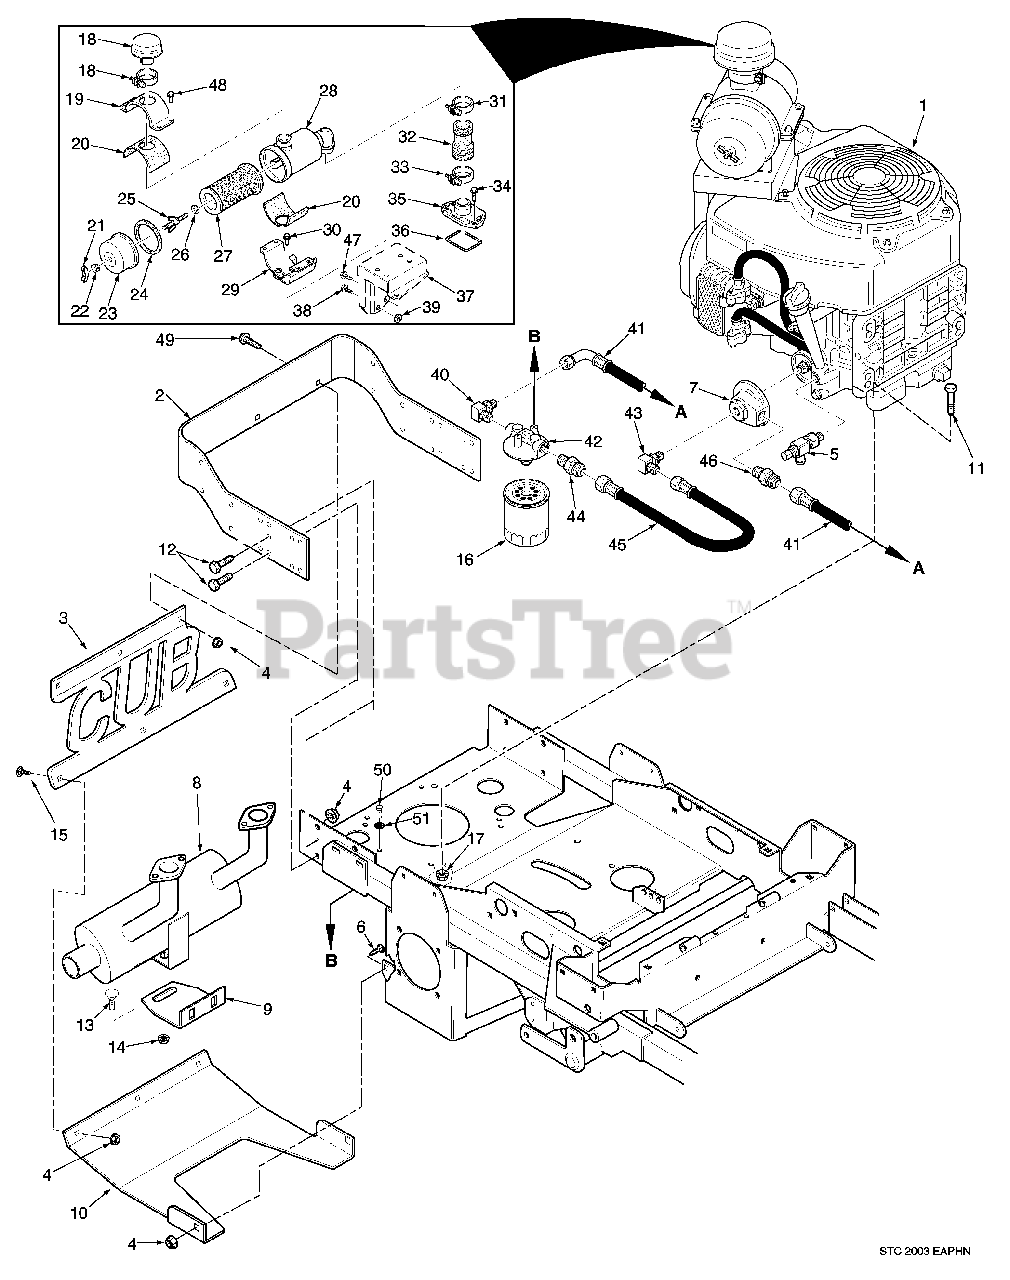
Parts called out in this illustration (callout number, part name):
1	Engine, Honda 24 HP (GXV670TAF2)
2	Bumper, Rear
3	Shield, Rear
4	Nut, Serr. Flange 3/8-16
5	Extension, Oil Drain 2.7"
6	Bolt, Carr. 3/8-16 x 1"
7	Adapter, Oil Filter
8	Muffler, Honda
9	Bracket, Muffler
10	Plate, Skid
11	Bolt, Hex Head 5/16-18 x 1-1/2"
12	Bolt, Hex Head 3/8-16 x 1"
13	Bolt, Hex Head 5/16-18 x 3/4"
14	Nut, Serr. Flange 5/16-18
15	Bolt, Carr. 3/8-16 x 3/4"
16	Oil Filter
17	Nut, Serr. Flange 5/16-18
18	Pre-Cleaner, Engine Air
19	Holder, Air Cleaner Upper
20	Rubber, Air Cleaner Holder
21	Wing Nut - 16mm
22	Grommet, Air Cleaner
23	Cover, Air Cleaner
24	Seal, Air Cleaner
25	Bolt, Air Cleaner
26	Washer, Air Cleaner
27	Element, Air Cleaner
28	Housing, Air Cleaner
29	Holder, Air Cleaner Lower
30	Bolt, Flange (6mm x 16)
31	Band, Air Cleaner Connecting Tube
32	Tube, Air Cleaner Connecting
33	Band, Air Cleaner Connecting Tube
34	Bolt, Flange (6mm x 28)
35	Joint B, Connecting Tube
36	Seal, Air Cleaner Housing
37	Stay, Engine Air Cleaner
38	Bolt, Flange (6mm x 14)
39	Collar, Seat
40	Elbow, 90 Degree 3/8 - 3/8
41	Hose, Remote Oil Filter Inlet
42	Filter Head
43	Elbow, 90 Degree 3/8 - 3/8
44	Tube, Union 1/2 - 3/8
45	Hose, Remote Oil Filter Return
46	Tube, Union 1/2 - 3/8
47	Bolt, Flange (8mm x 16)
48	Bolt, Flange (6mm x 12)
49	Bolt, 3/8-16 x 1" Torx
50	Bolt, Hex Head 1/4-20 x 5/8"
51	Lockwasher, 1/4" Spring
